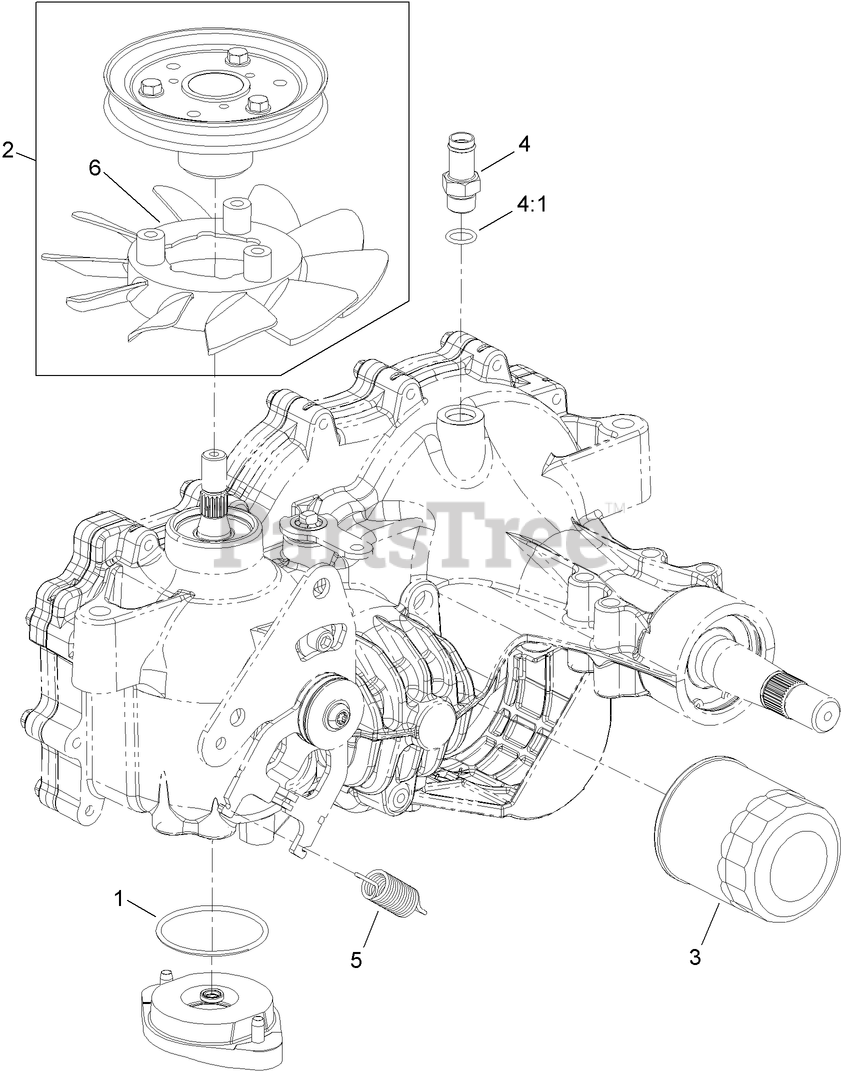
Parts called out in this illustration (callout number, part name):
1	O RING-SEAL
2	FAN AND PULLEY KIT
3	ELEMENT-OIL FILTER, HYD
4	ADAPTER-STRAIGHT
4:1	O-Ring
5	SPRING-EXTENSION
6	FAN-OFFSET, HYDROGEAR
